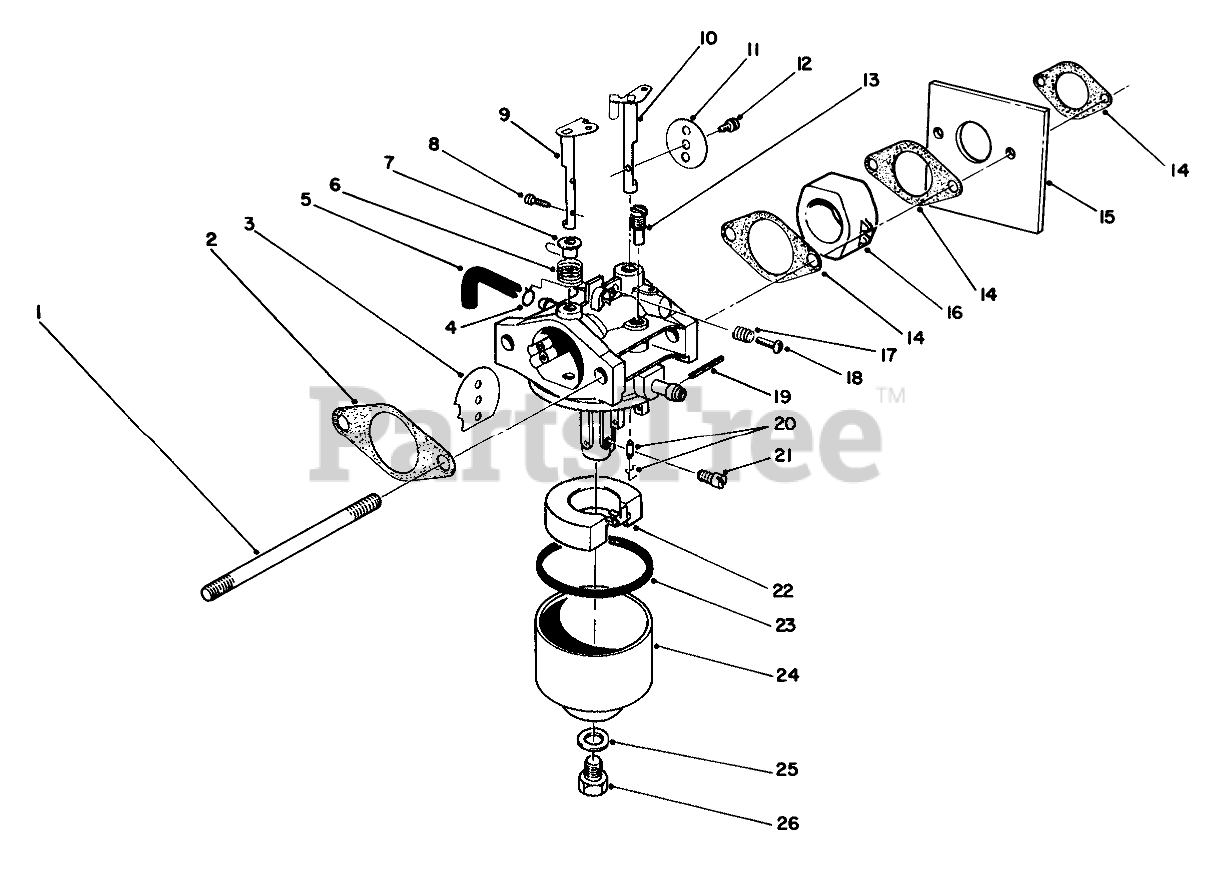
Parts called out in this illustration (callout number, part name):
1	STUD-CARBURETOR
2	GASKET-AIR CLEANER
3	PLATE
4	VENT TUBE
5	CLAMP
6	SPRING
7	BUSHING
8	SCREW
9	SHAFT-CHOKE
10	SHAFT
11	PLATE
12	Screw-Throttle
13	PILOT JET
14	GASKET-CARB
15	SHIELD-CARBURETOR
16	INSULATOR-CARBURETOR
17	SPRING-PILOT SCREW
18	SCREW
19	PIN-HINGE
20	NEEDLE
21	JET-MAIN
22	FLOAT
23	GASKET
24	BOWL - FLOAT
25	GASKET
26	SCREW
